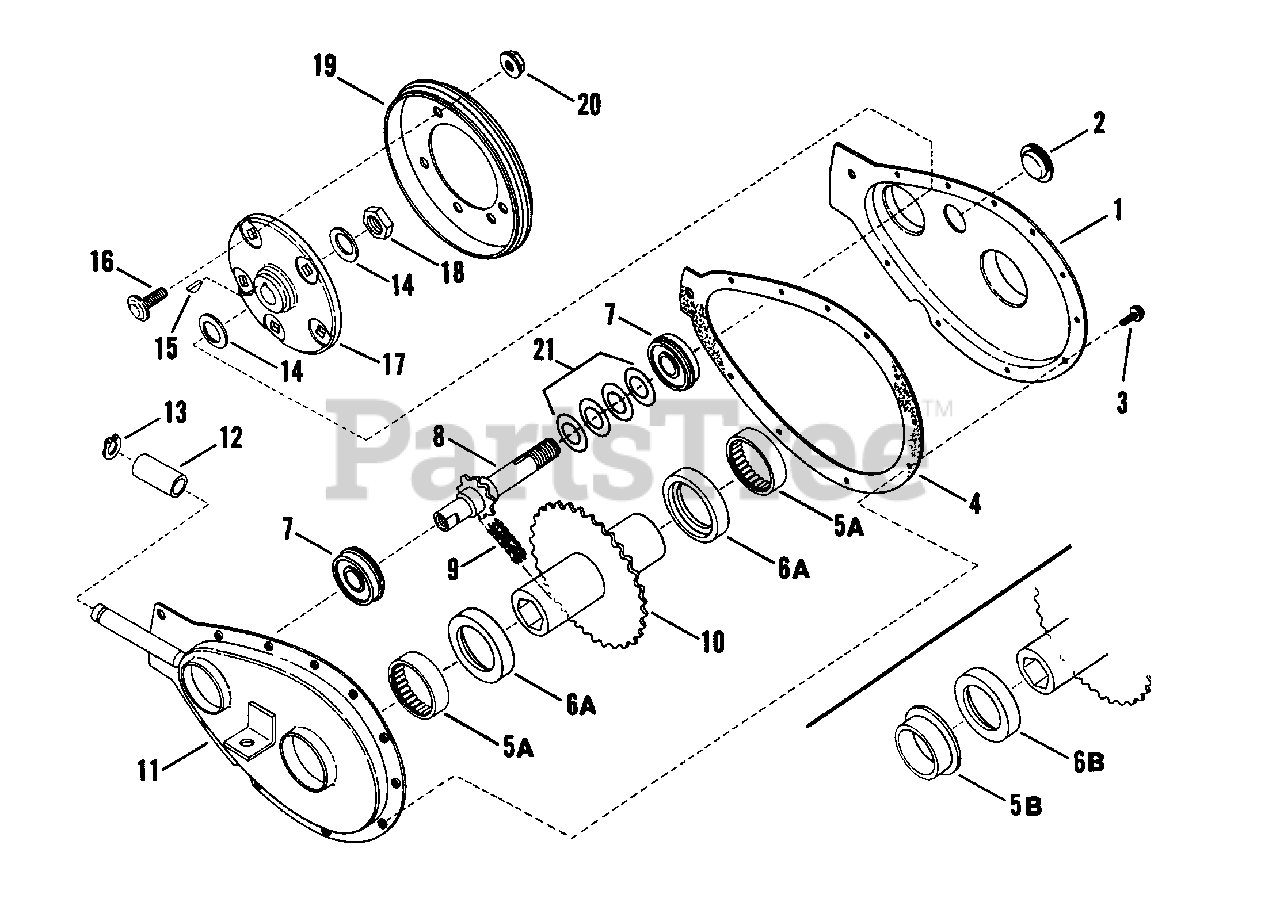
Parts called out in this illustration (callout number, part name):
2	PLUG, 3/4" Insert
3	SCREW, #10-24 x 1/2" Hex Washer Self-Tap (Torx)
4	GASKET
5A	BEARING, Needle 1.355" ID x 1.6245" OD x .5" Wide
5B	BUSHING
6A	WASHER, Thrust
6B	WASHER, Thrust
7	BEARING, Ball 5/8" ID x 1-3/8" OD
8	SPROCKET, Shaft
9	CHAIN, 46 Pitch (#35 Endless)
10	HUB, Sprocket
11	CASE, Sprocket
12	ROLLER
13	RING, Retaining
14	WASHER, Belleville
15	KEY,1/8 x 5/8" Woodruff
16	BOLT, 5/16-18 x 1/2" Short Neck Carriage, Grade 5
17	HUB
18	NUT, 5/8-18 Hex Jam Center Lock
19	DISC, Driven (R/B 7018782)
20	NUT, 5/16-18 Hex Flange Lock
21	WASHER, Shim
